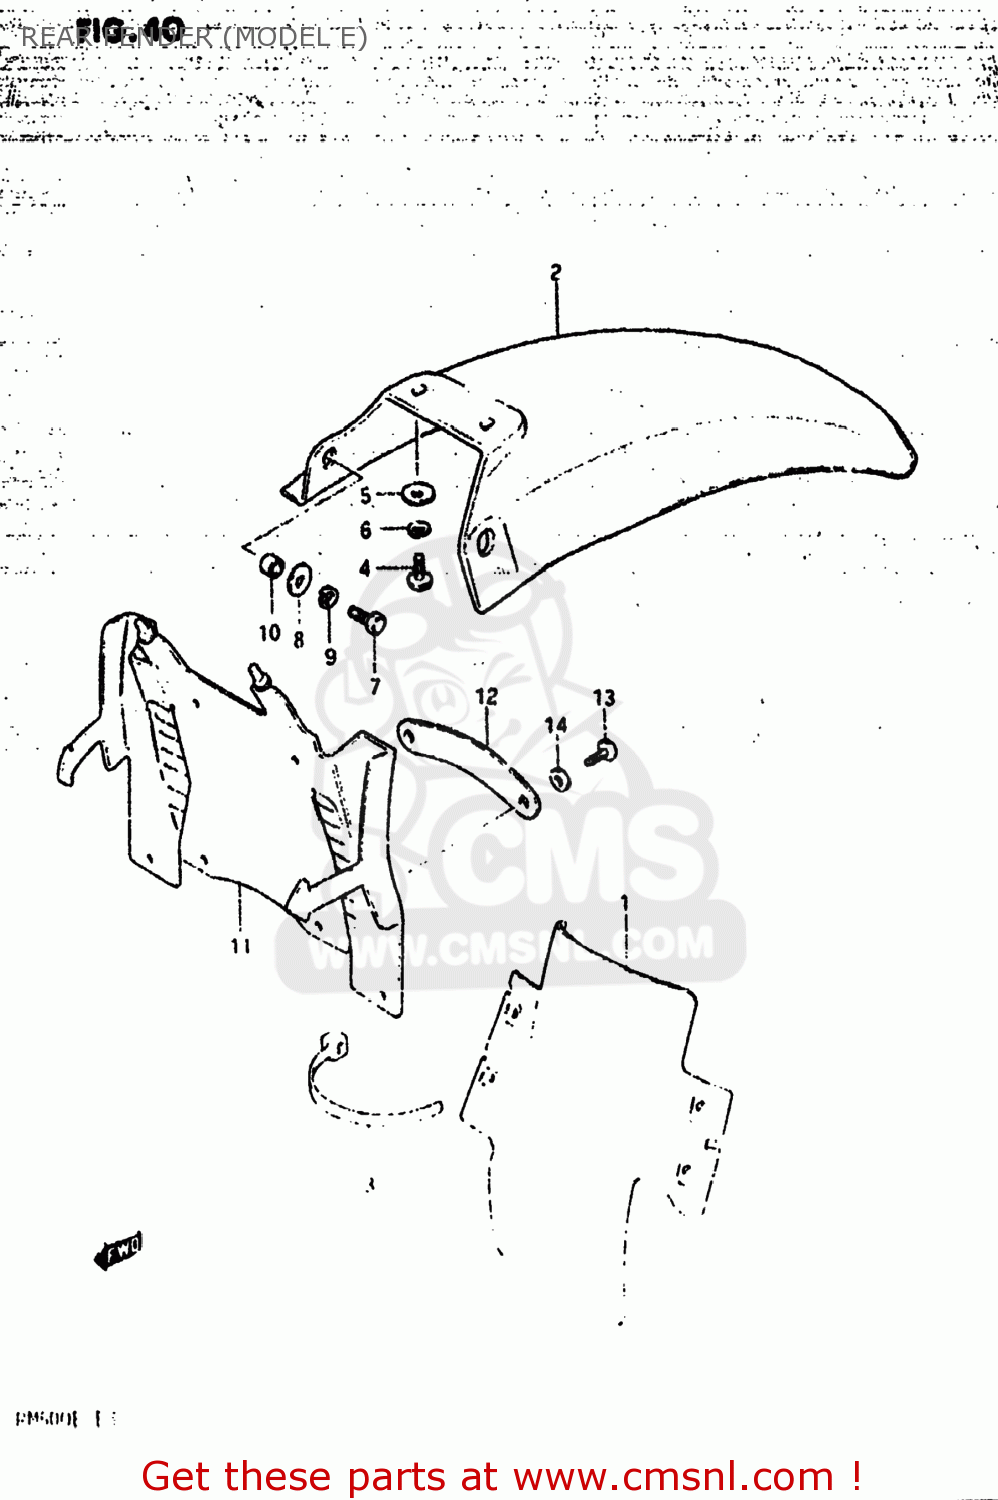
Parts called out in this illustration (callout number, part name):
1	REAR FENDER,FRONT
2	FENDER,REAR
3	CLAMP
4	SCREW
5	WASHER (6.5X20X1.2)
6	LOCK WASHER
7	BOLT, UPPER
8	WASHER (6.5X20X1.2)
9	LOCK WASHER
10	SPACER
11	MUD GUARD,REAR FENDER
12	PLATE,MUD GUARD
13	SCREW
14	WASHER,5MM
